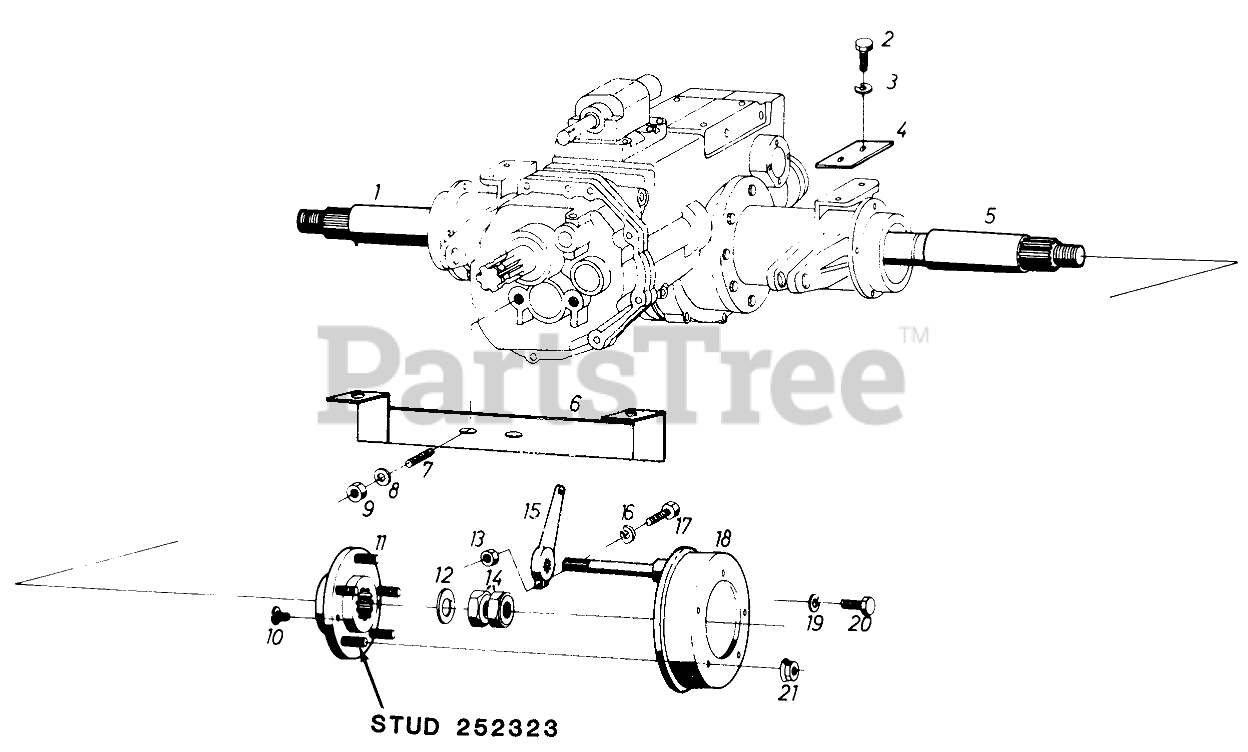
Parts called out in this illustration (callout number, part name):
1	Axle Right
2	Screw
3	Washer
4	Plate
5	Axle Left
6	Support Assy.
8	Washer
10	Screw
11	Hub Assy., Rear
12	Flat Washer
15	Brake Lever
16	Lockwasher
18	Brake Drum
19	Washer
20	Screw
